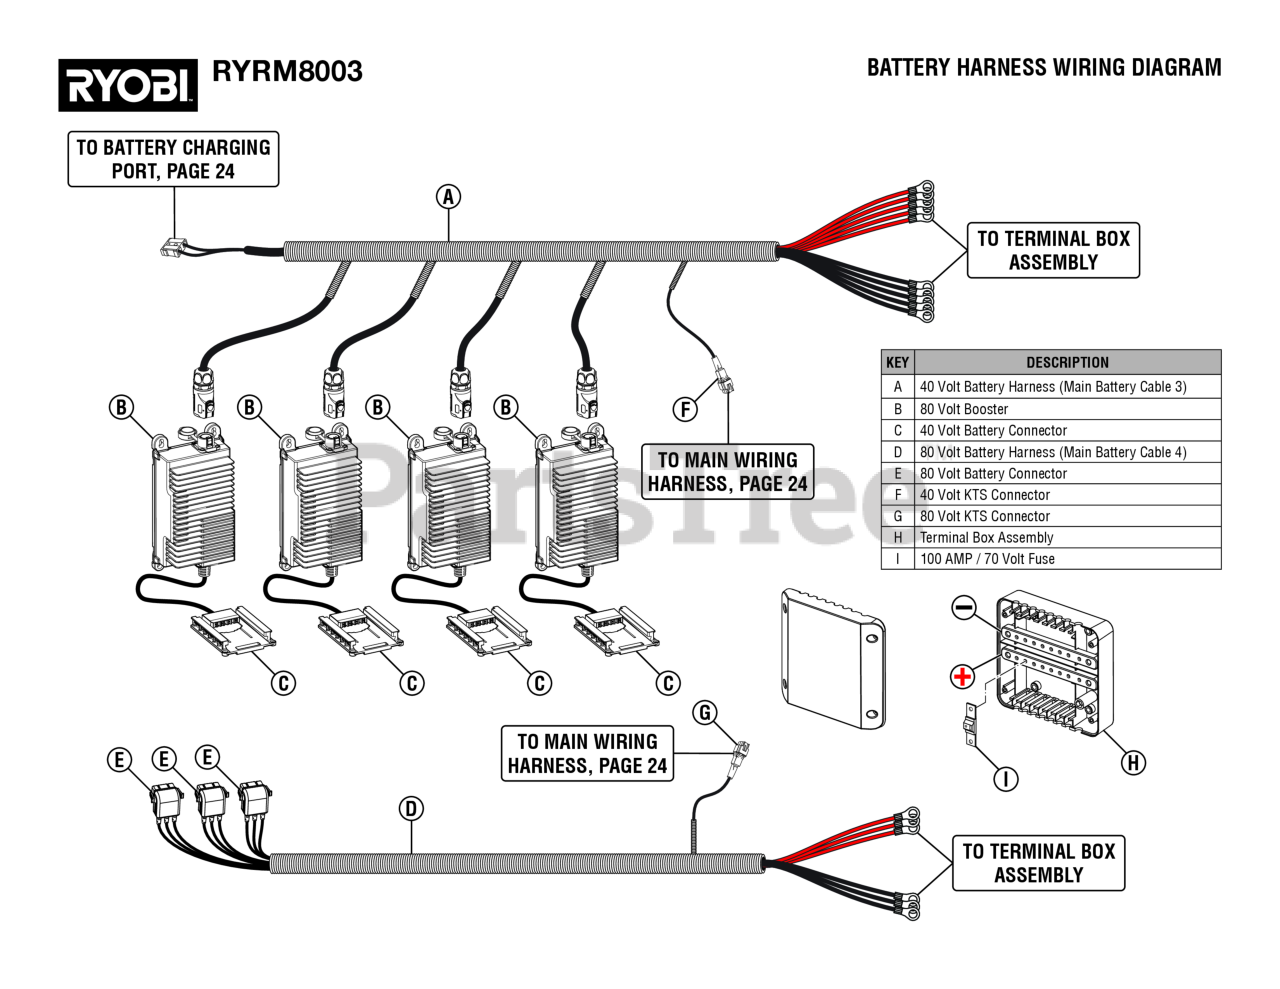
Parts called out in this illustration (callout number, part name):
B	80 Volt Booster
C	40 Volt Battery Connector
E	80 Volt Battery Connector
F	40 Volt KTS Connector
G	80 Volt KTS Connector
H	Terminal Box Assembly
I	100 AMP / 70 Volt Fuse
